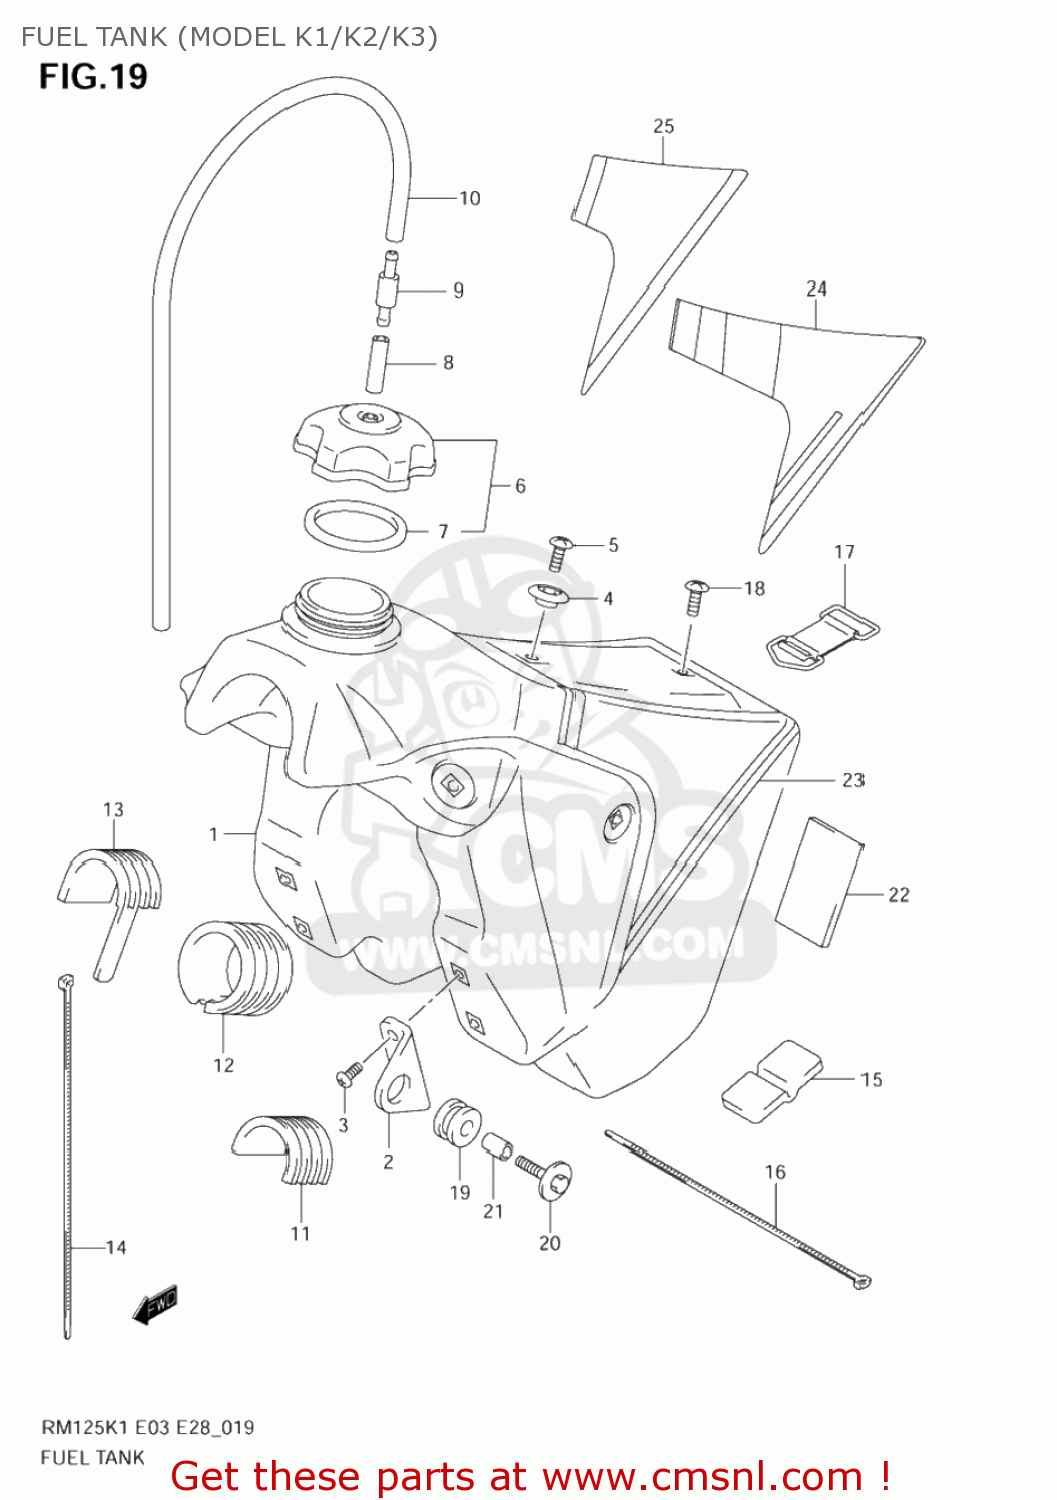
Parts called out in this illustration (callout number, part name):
1	TANK COMP,FUEL
2	BRACKET,FUEL TANK FR
3	SCREW 6X12
4	HOOK,SEAT FR
5	SCREW
6	CAP SET,FUEL TANK
7	GASKET,CAP (NAS)
8	HOSE(5X8.2X600)
9	PLUG,FUEL TANK BREATHER
10	HOSE(5X8.2X600)
11	CUSHION,FUEL TANK UPR
12	CUSHION,FUEL TANK NO.1
13	CUSHION,FUEL TANK
14	CLAMP(L:300)
15	CUSHION,FUEL TANK RR
16	CLAMP(L:250)
17	BAND,FUEL TANK RR
18	SCREW
19	CUSHION,MUFFLER
20	BOLT(6X30)
21	SPACER(6.5X9X13.5)
22	PROTECTOR(40X85X5)
23	TAPE SET,FUEL
24	TAPE SET,FUEL TANK
25	TAPE SET,FUEL TANK
